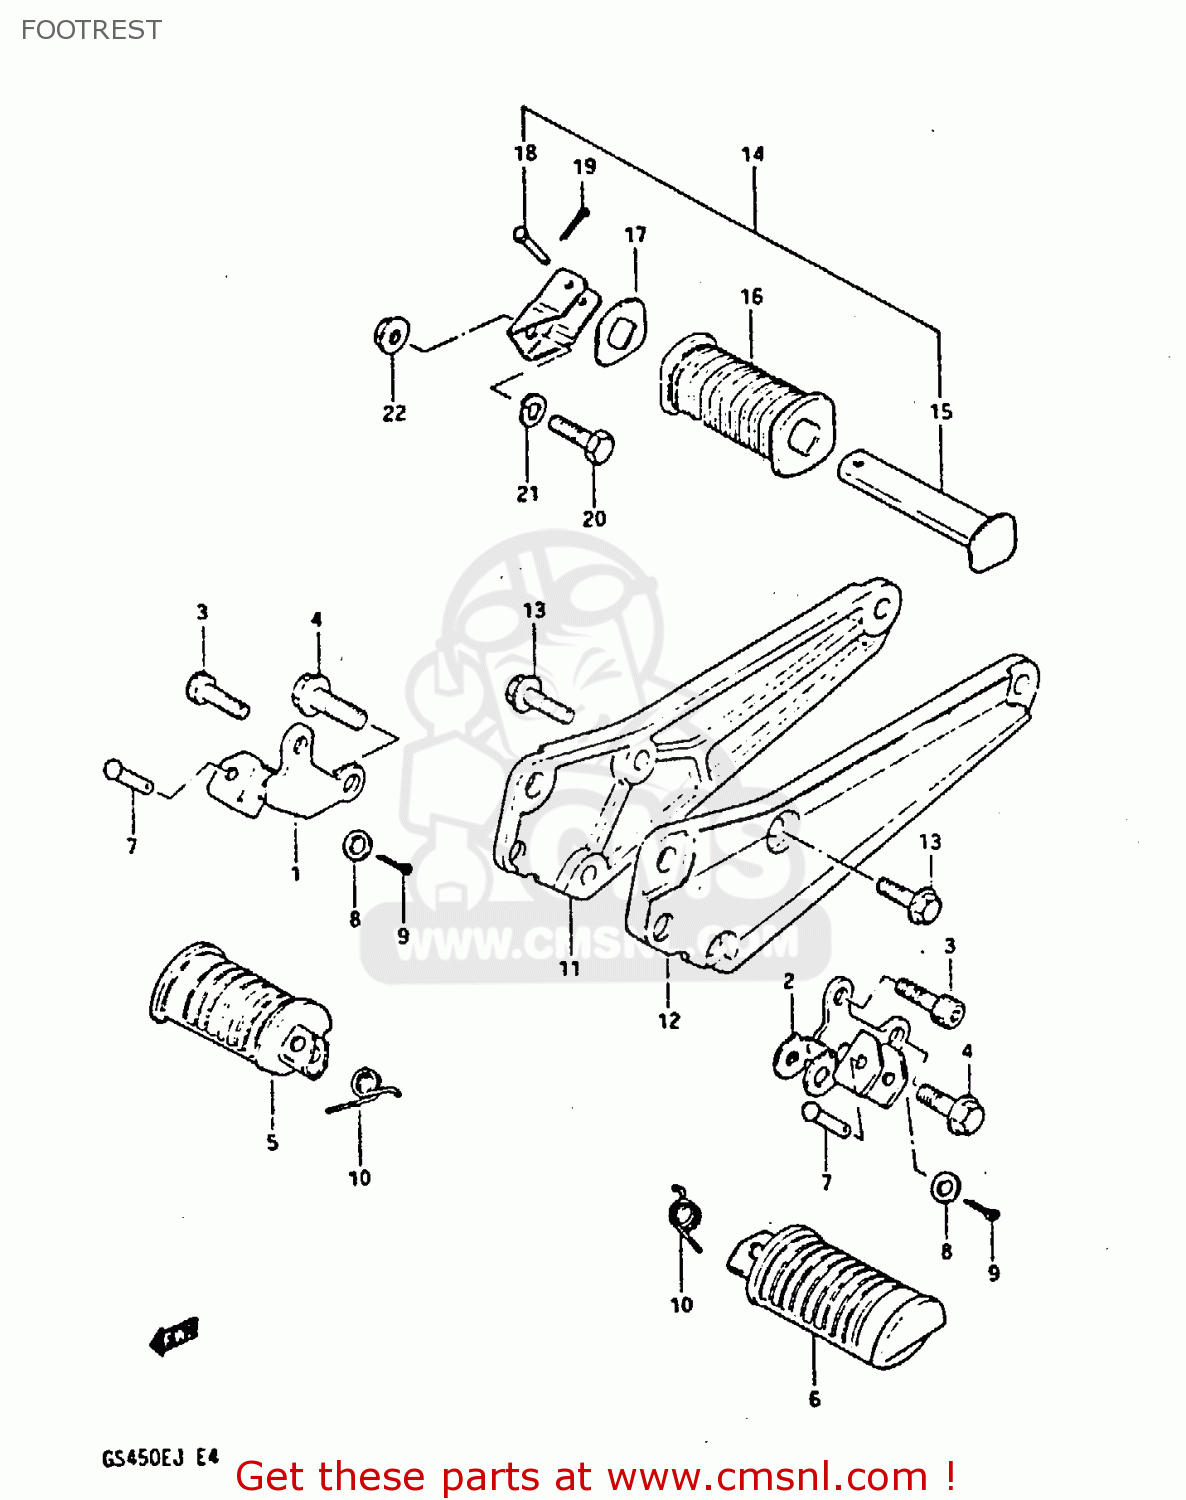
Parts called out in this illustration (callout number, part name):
1	BAR,FR FOOTREST,R
2	BAR,FRONT FOOTREST,LEFT
3	BOLT
4	BOLT
5	RUBBER,PILLION FOOTREST,R
6	RUBBER,PILLION FOOTREST,L
7	PIN
8	WASHER
9	PIN 20X20
10	SPRING
11	BRACKET,MUFFLER,RIGHT
12	BRACKET,MUFFLER,LEFT
13	BOLT
14	FOOTREST ASSY,PILLION,R
15	BAR,REAR FOOTREST,LEFT
16	RUBBER,PILLION FOOTREST
17	WASHER,FOOTREST RUBBER
18	PIN
19	PIN 20X20
20	BOLT,M10X1.25X
21	WASHER,LOCK,10
22	NUT
